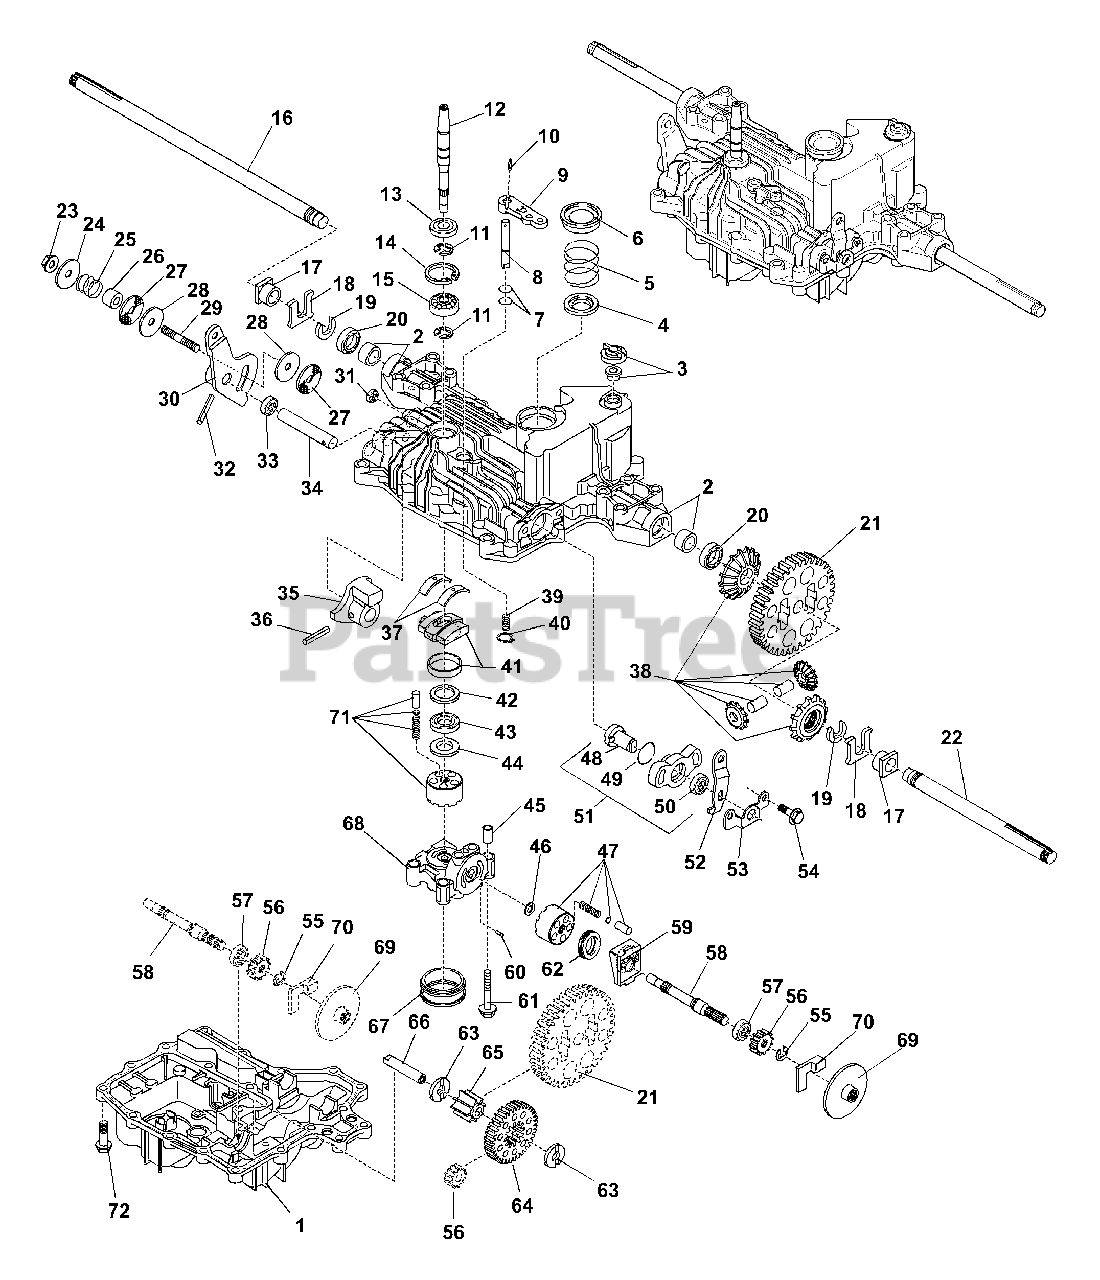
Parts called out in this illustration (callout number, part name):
1	LOWER HOUSING
2	UPPER HOUSING CMP.
3	VENT VALVE 15
5	SPRING - FILTER
6	SEALING CAP 50
7	O-RING, 1A P10A
8	SHAFT - BYPASS
9	LEVER - BYPASS
10	PIN 3.0A*20
11	RING E15
13	SEAL TC153507
15	BEARING 6202C3
16	AXLE SHAFT R
17	BUSHING 19*21
18	THRUST WASHER
20	SEAL 19*32*8
22	AXLE SHAFT L
23	LOCK NUT 10
24	WASHER 10*36*2.8
25	SPRING - FRICTION
26	COLLAR 10*22*14.5
27	WASHER 10*40*4
28	FRICTION PLATE CMP.
30	CONTROL LEVER
31	CAP, SEALING 18
32	PIN 6.0A*40
33	SEAL TC162606
34	CONTROL SHAFT
35	CONTROL ARM A
36	PIN 6.0A*32
37	THRUST BEARING
38	DIFF. GEAR KIT
41	SWASH PLATE CMP.
42	THRUST PLATE B
43	BEARING K81105
44	THRUST PLATE A
45	KNOCK PIN 12*22
46	WASHER 12*24*1
47	CYLINDER BLOCK CMP.
48	SHAFT-BRAKE
49	PACKING P29
50	SEAL TC162606
51	BRAKE CAM KIT
53	PLATE-BRAKE
57	BEARING 6202UC3
58	MOTOR SHAFT
62	BEARING 51106
63	WASHER 12*32*3.2
64	REDUCTION GEAR
65	FINAL PINION
66	REDUCTION SHAFT
67	FILTER
68	CENTER CASE B CMP.
71	CYLINDER BLOCK CMP.
72	TAPPING SCREW 8*30
